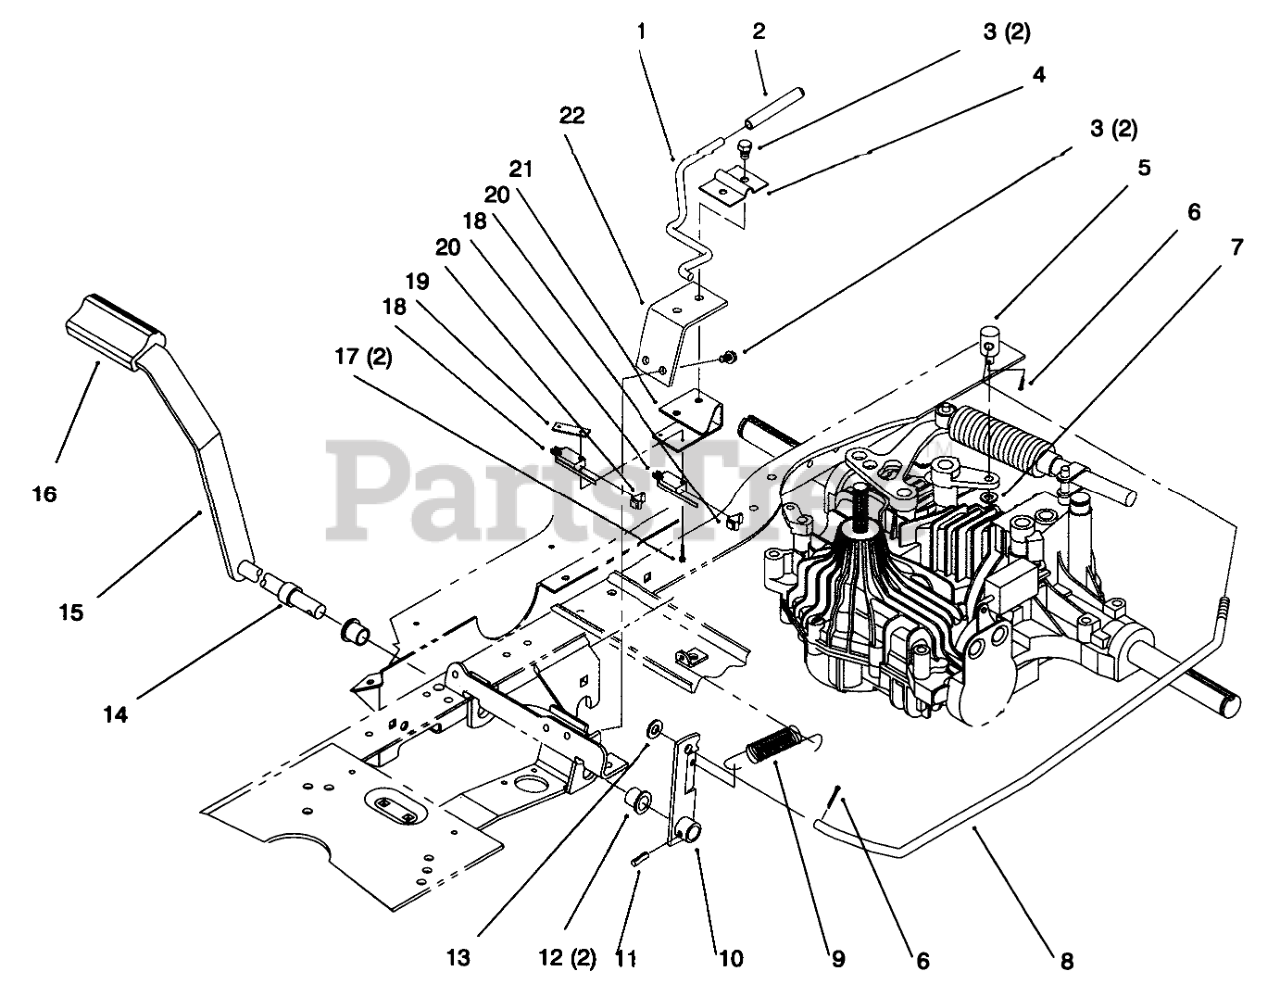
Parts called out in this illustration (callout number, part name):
1	ROD - PARKING BRAKE
2	GRIP - PARKING BRAKE
3	Screw-HH
4	BRKT-PARKING BRAKE
5	TRUNNION - BRAKE
6	PIN-COTTER
7	WASHER-PLAIN
8	ROD - BRAKE
9	SPRING-EXTENSION
10	WA - BRAKE LEVER
11	PIN-SPRING
12	BUSHING-FLANGE
13	WASHER-FLAT
14	SPACER-BRAKE
15	LEVER - BRAKE WA
16	PAD-PEDAL
16	Tube-Brake
16	Lever-Brake
17	SCREW-HH
18	SWITCH-MICRO
19	NUT-SPEED
20	PLUNGER-SEAL
21	BRKT - BRAKE SWITCH
22	SUPPORT - P. BRAKE
